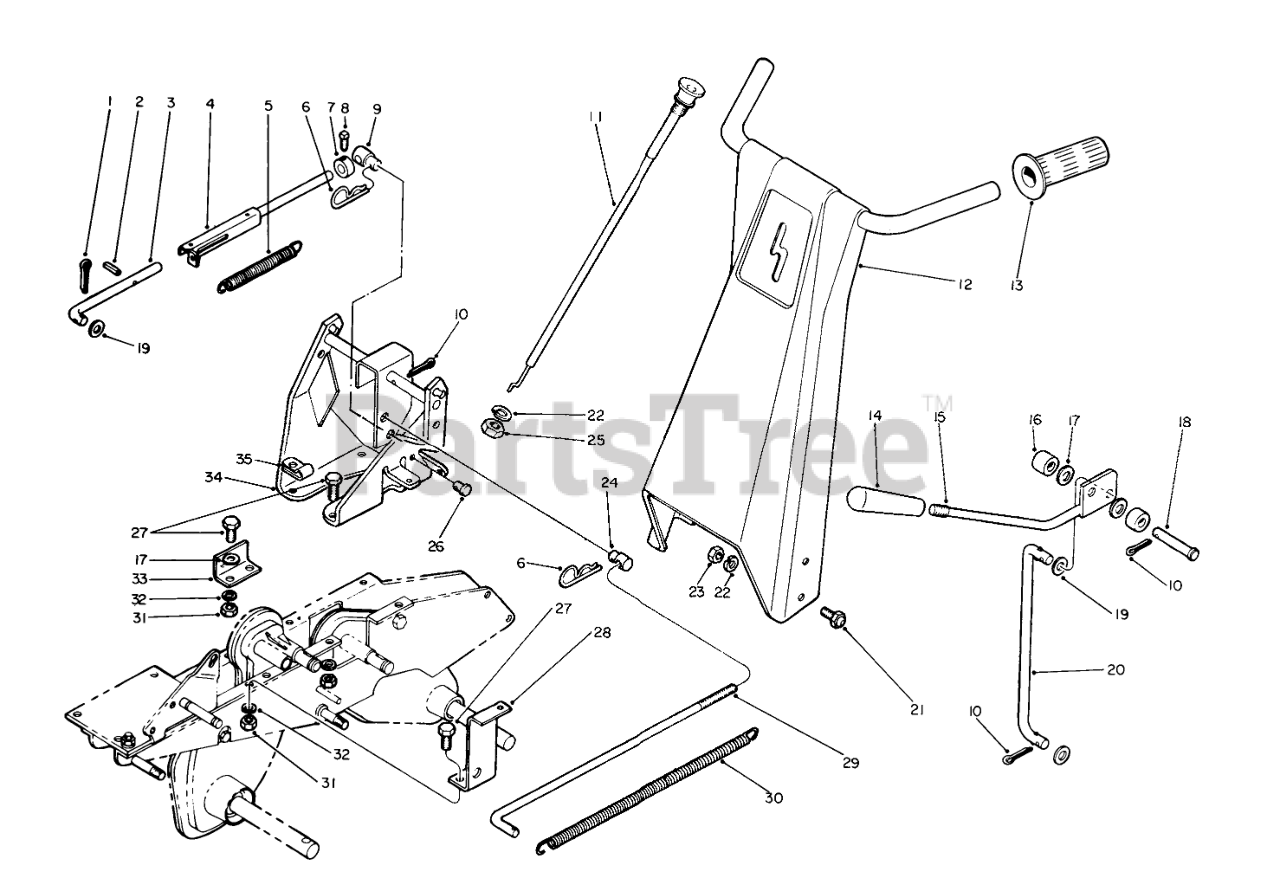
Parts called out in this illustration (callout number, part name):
1	PIN-COTTER
2	PIN-ROLL, SLOTTED
3	Tine Drive Link
4	Rear Tine Drive Link
5	Spring
6	Spring Clip
7	Stop Collar
8	Square Hd. Setscrew
9	Trunnion
10	PIN-COTTER
11	Throttle Control
12	Handle w/Decal
13	Grip
14	Knob
15	Clutch Handle
16	Rubber Disc
17	WASHER-PLAIN
18	Clevis Pin
19	WASHER-FLAT
20	Control Link
21	SCREW-HH
22	WASHER-LOCK
23	NUT-HEX
24	Trunnion
25	NUT-HEX
26	Clevis Pin
27	SCREW-HH
28	Bracket
29	Wheel Drive Link
30	Spring-Wheel Drive
31	NUT-HEX
32	WASHER-LOCK
33	Pivot Bracket
34	Handle Support
35	Cable Clamp
